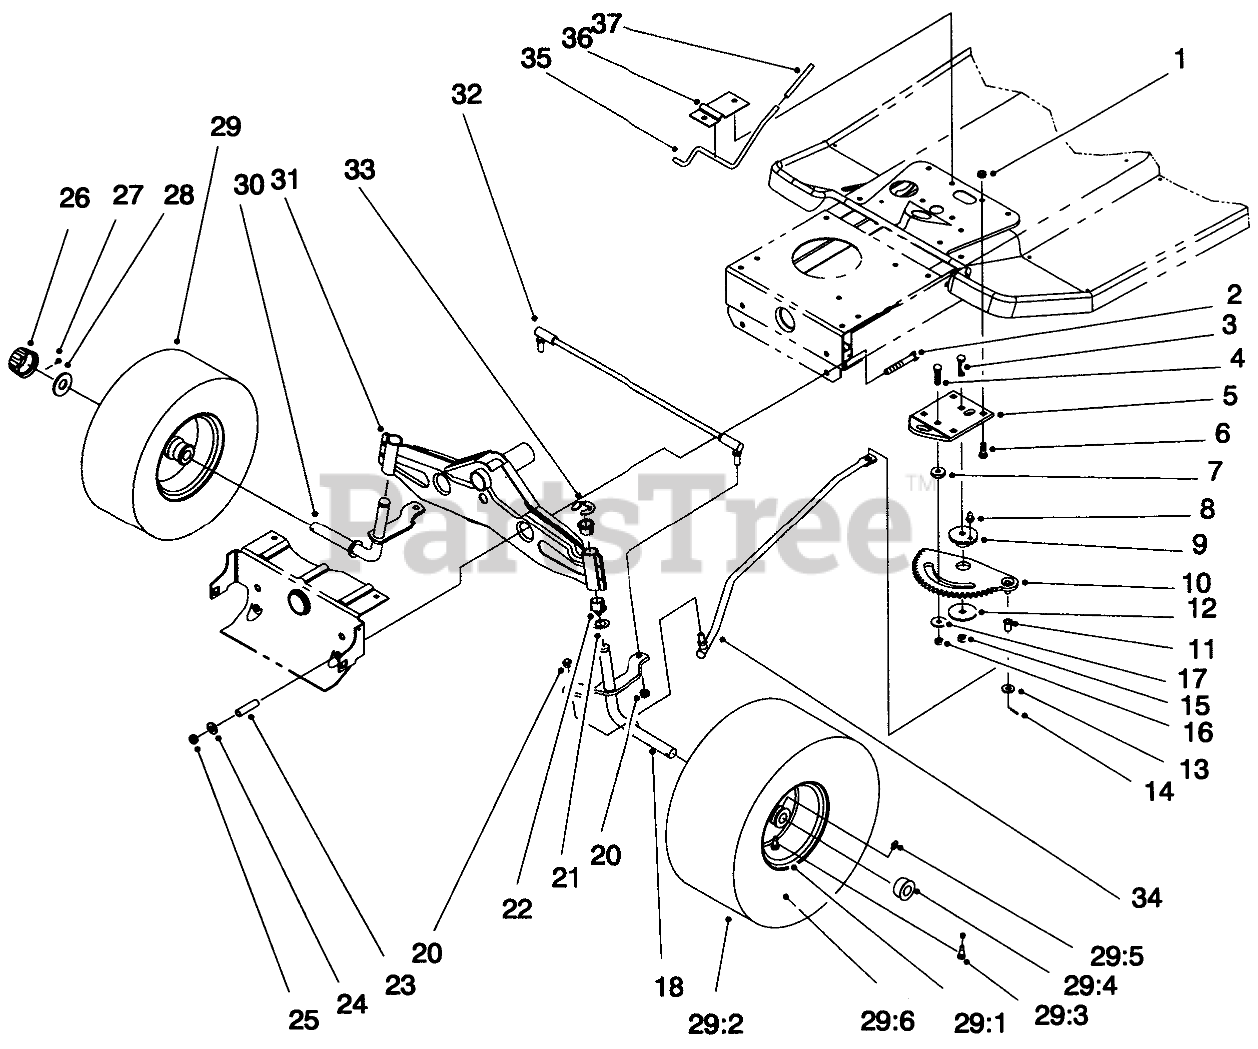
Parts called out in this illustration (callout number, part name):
1	NUT-LOCK, NI
2	SCREW-HH
3	SCREW-CARR
4	SCREW-CARR
5	Bracket-Steering Rack
6	BOLT-CARR
7	SPACER-RACK, STEERING
8	FITTING-GREASE
9	BUSHING-ECCENTRIC
10	RACK-STEERING
11	BUSHING-FLANGED, NYLON
12	WASHER-BEARING
13	WASHER-FLAT
14	PIN-COTTER
15	NUT-LOCK, NI
16	NUT-LOCK, NI
17	WASHER-PIVOT
18	Spindle-L.H.
20	NUT-HEX
21	WASHER-THRUST
22	BUSHING
23	SPACER
24	WASHER-FLAT
25	NUT-LOCK, NI
26	CAP-HUB
27	PIN-COTTER
28	WASHER-PLAIN
29:1	RIM ASM
29:2	TIRE 15 X 6.00 X 6
29:3	STEM-VALVE
29:4	BEARING-WHEEL
29:5	FITTING-GREASE
29:6	TUBE-INNER
30	Spindle-R.H.
31	Axle-Front
32	TIE ROD ASM
33	E-RING
34	LINK-DRAG
35	ROD-BRAKE, PARKING
36	Bracket-Parking Brake
37	GRIP-BRAKE, PARKING
